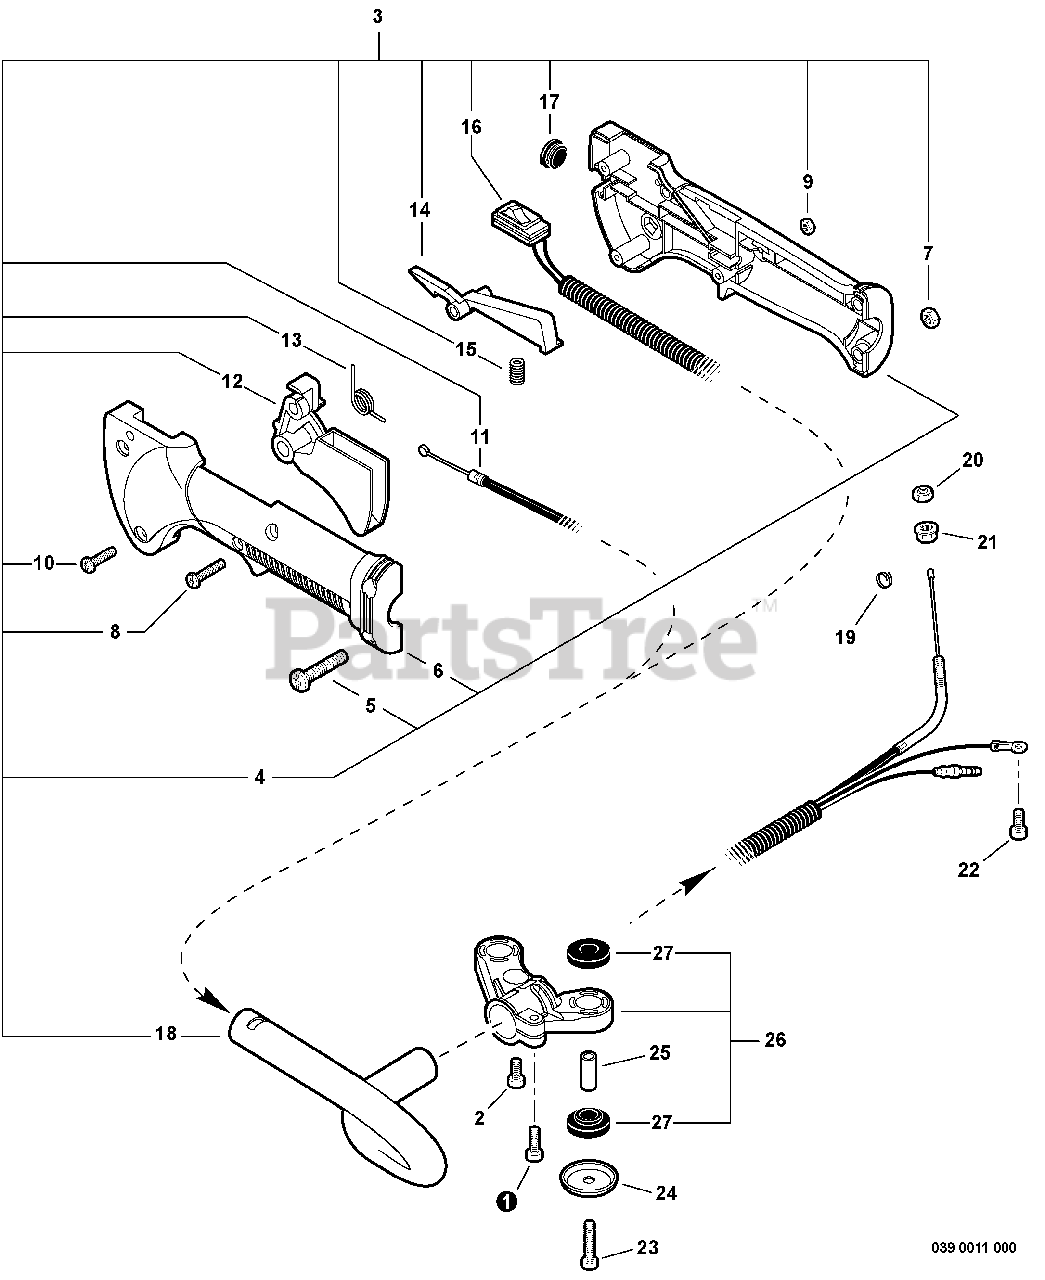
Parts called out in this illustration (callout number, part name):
1	BOLT, TORX 5×16
2	BOLT, TORX 5×12
3	HANDLE ASSY, REAR
4	CONTROL HANDLE KIT
5	SCREW M5×22
6	CONTROL HANDLE - LEFT
7	NUT, LOCK M5
8	SCREW M4×23
10	SCREW, TAPPING 4×16
11	CABLE, THROTTLE
12	TRIGGER, THROTTLE
13	SPRING, TORSION
14	LOCKOUT, THROTTLE
15	SPRING, COMPRESSION
16	SWITCH ASSY, ON-OFF
17	PLUG, RUBBER
18	HANDLE, REAR
21	NUT, FLANGE M6×1
22	BOLT, TORX 4×8
23	BOLT, TORX 6
24	WASHER 6
25	COLLAR 6
26	SUPPORT ASSY, HANDLE
27	CUSHION
